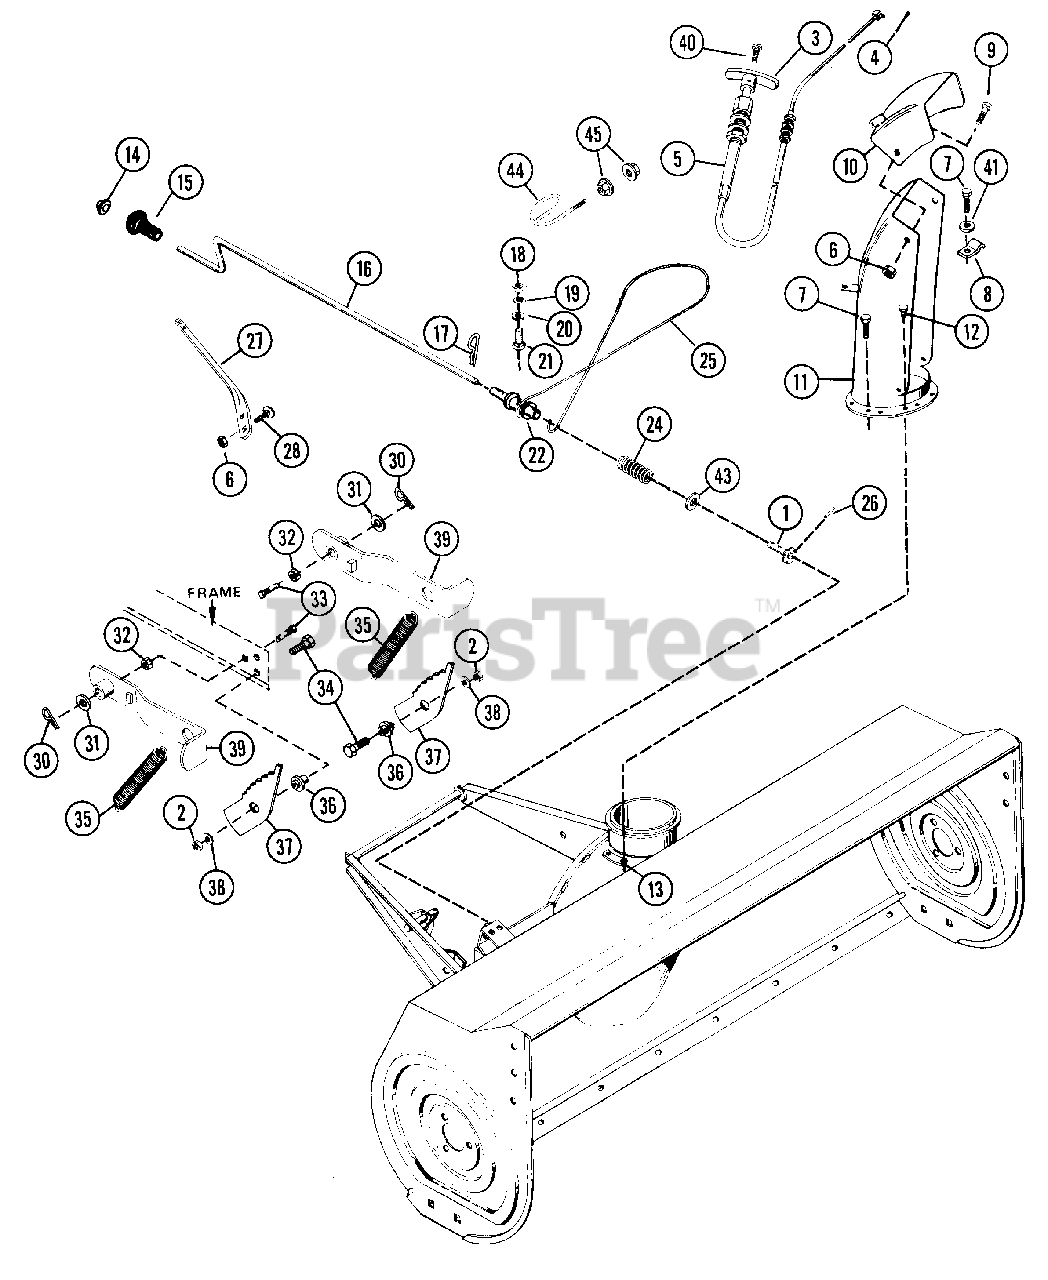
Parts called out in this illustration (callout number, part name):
1	ARM, DISC
2	NUT, LOCK 5/16-18
3	HANDLE, TEE
4	PIN, COTTER .09X.75
5	CABLE, CONTROL
6	NUT, LOCK 3/8-16
7	SCREW, TAPTITE 10-24X.75
8	CLAMP, CABLE
9	BOLT, HEX 3/8-16X.75
10	DEFLECTOR, CHUTE
11	CHUTE, DISCHARGE
12	SCREW, TAPTITE 10-24X.375
13	CLAMP, CHUTE
14	CAP
15	KNOB
16	CRANK, CHUTE CONTROL
17	HAIR PIN, INTERNAL
18	NUT, HEX 1/4-20
19	WASHER, LOCK 5/16 REG.
20	WASHER, FLAT .281X.625X.065
21	BOLT, 1/4-20X.625 RD HD SQ NK
22	SPOOL
24	SPRING, COMPRESSION
25	CABLE
26	PIN, SPRING .187X1.000
27	SUPPORT
28	BOLT, 3/8-16X1.00 RD HD SQ NK
30	HAIRPIN, INTERNAL 3/32
31	WASHER, FLAT .56X1.87X.109
32	NUT, LOCK 1/2-13
33	STUD, WEIGHT
34	BOLT, HEX 5/16-18X1.25
35	SPRING, EXTENSION
36	SPACER
37	SPRING ASSIST CONTROL
38	WASHER, FLAT .406X.812X.065
39	ARM, SPRING
40	SCREW, MACHINE 10-32X.50
41	WASHER, FLAT .219X.438X.049
43	WASHER, .635/.645X1.005X.062
44	CABLE SUPPORT
45	NUT, LOCK 1/4-20
NS	DECAL, DANGER HAND
NS	DECAL, CHUTE CRANK
NS	DECAL, CAUTION
